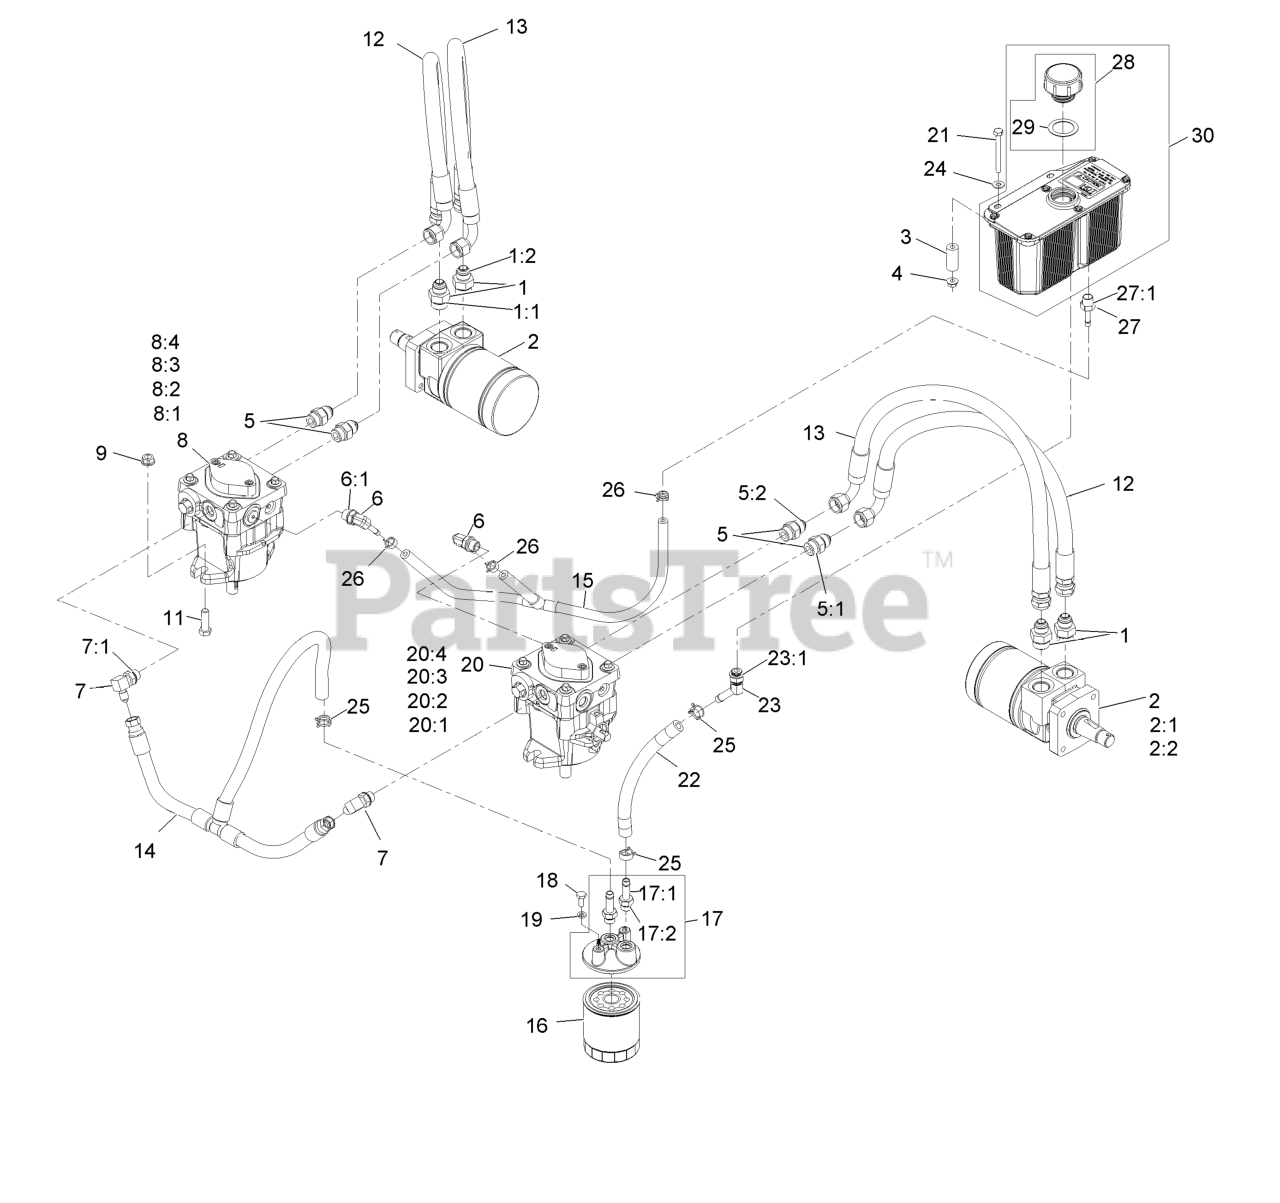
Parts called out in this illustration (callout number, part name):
1	FITTING-STRAIGHT
2	HYD MOTOR ASM
2:1	BEARING AND SEAL KIT
2:2	SEAL KIT
5	FITTING-STRAIGHT
6	ELBOW-90 DEG
7	FITTING-ELBOW, 90 DEG
8	LH HYD PUMP ASM
8:1	INPUT SHAFT KIT
8:2	BEARING-THRUST
8:3	CYLINDER BLOCK KIT
8:4	SEAL OVERHAUL KIT
9	NUT-FLANGE
11	SCREW-HH
13	HOSE-PRESSURE, HIGH
14	CHARGE HOSE ASM
15	CASE DRAIN HOSE ASM
16	FILTER-25 MICRON, BI-DIRE
16	ELEMENT-FILTER, WINTER
17	FILTER HEAD ASM
17:1	ADAPTER-STRAIGHT
18	SCREW-HH
19	WASHER-LOCK
20	RH HYD PUMP ASM
20:1	INPUT SHAFT KIT
20:2	BEARING-THRUST
20:3	CYLINDER BLOCK KIT
20:4	SEAL OVERHAUL KIT
21	SCREW-HH
22	HOSE-CHARGE
23	FITTING-BARBED, 45 DEG
24	WASHER-FLAT
25	CLAMP-HOSE
26	CLAMP-HOSE
27	ADAPTER-STRAIGHT
28	KIT,HYD RES CAP W/GASKET
29	GASKET-CAP
30	HYD RESERVOIR ASM
